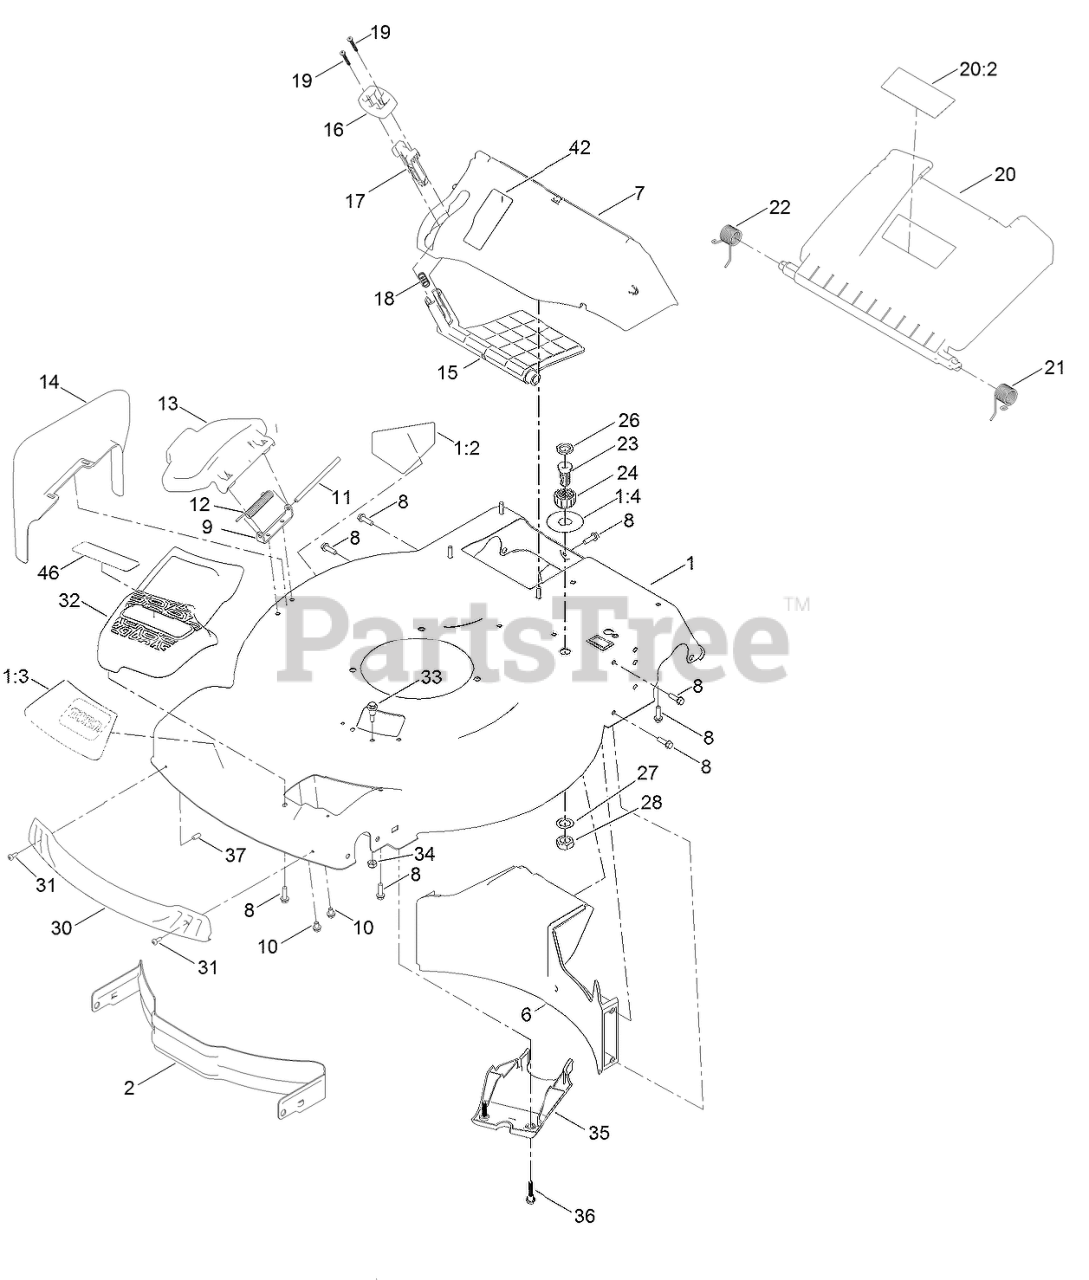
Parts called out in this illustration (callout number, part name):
1	HOUSING ASM
1:2	DECAL-DANGER
1:3	DECAL-DECK
1:4	DECAL-QUICK WASH
2	BAFFLE-FRONT
6	BAFFLE-REAR
7	CHUTE-RECYCLE
8	SCREW-HWH
9	BRACKET-COVER
10	SCREW-HWH
12	SPRING-TORSION
13	DEFLECTOR-SIDE
14	CHUTE-DISCHARGE, SIDE
15	DEFLECTOR-RECYCLE
16	KNOB-RECYCLE
17	LATCH-RECYCLE
18	SPRING-COMPRESSION
19	SCREW-PPH
20	REAR DOOR ASM
20:2	DECAL-WARNING
21	SPRING-TORSION
22	SPRING-TORSION
23	PORT-WASHOUT
24	COUPLING-HOSE, WASHOUT PORT
26	WASHER-SEAL, WASHOUT PORT
27	WASHER-LOCK
28	NUT-JAM
30	BUMPER
31	SCREW-FORMING, THREAD
32	COVER-BELT, FRONT
33	BOLT-SHOULDER
34	NUT-LOCK, NI
35	COVER-BELT, FRONT
36	SCREW-SHOULDER, HHF
37	CAP-PLUG
46	DECAL-BELT COVER, POWEREVERSE
